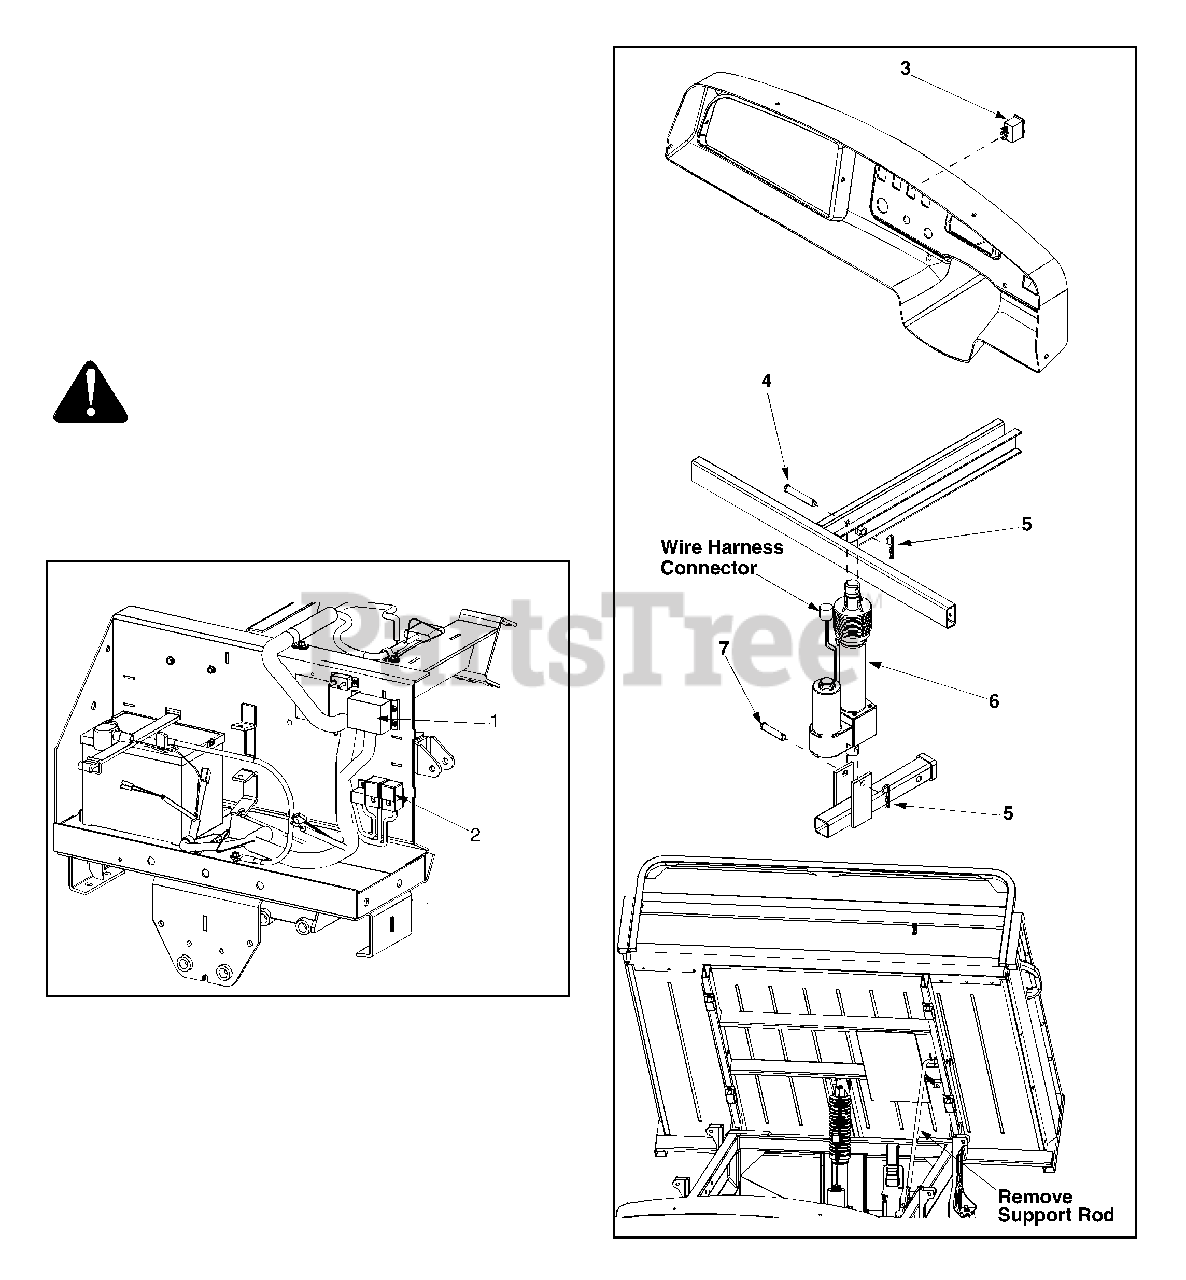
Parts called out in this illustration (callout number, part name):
1	Fuse 30 Amp
2	Relay 12V 40A
3	Cargo Box Switch
4	Clevis Pin 3.0"
5	Internal Cotter Pin
6	Electric Lift Actuator
7	Clevis Pin 2.25"
